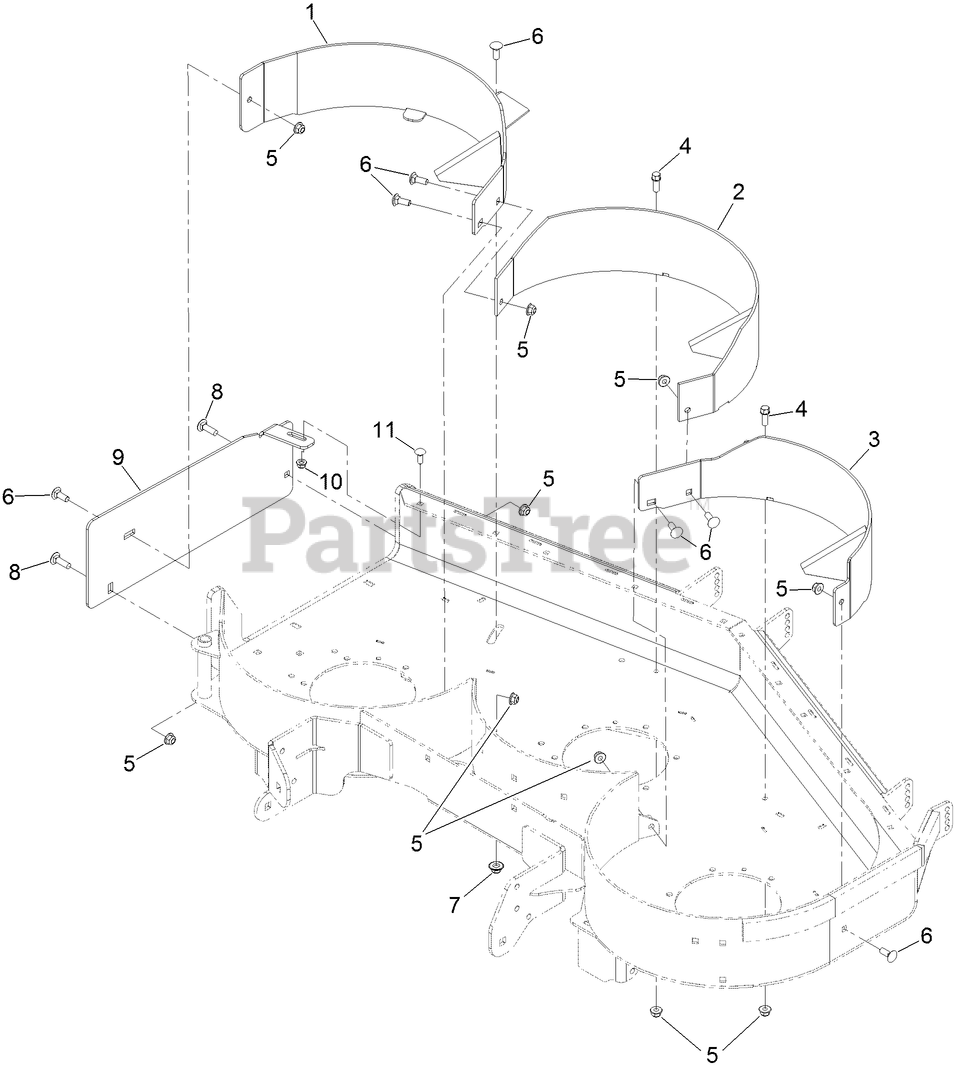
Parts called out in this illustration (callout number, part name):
1	BAFFLE ASM-RH, 52
2	BAFFLE-CENTER
3	BAFFLE-LH
5	NUT-HF, NI
6	BOLT-CARR
7	NUT-FLANGE, NI
8	BOLT-CARR
9	PLATE-COVER, DISCHARGE
10	NUT-HF, NI
11	SCREW-CARR
